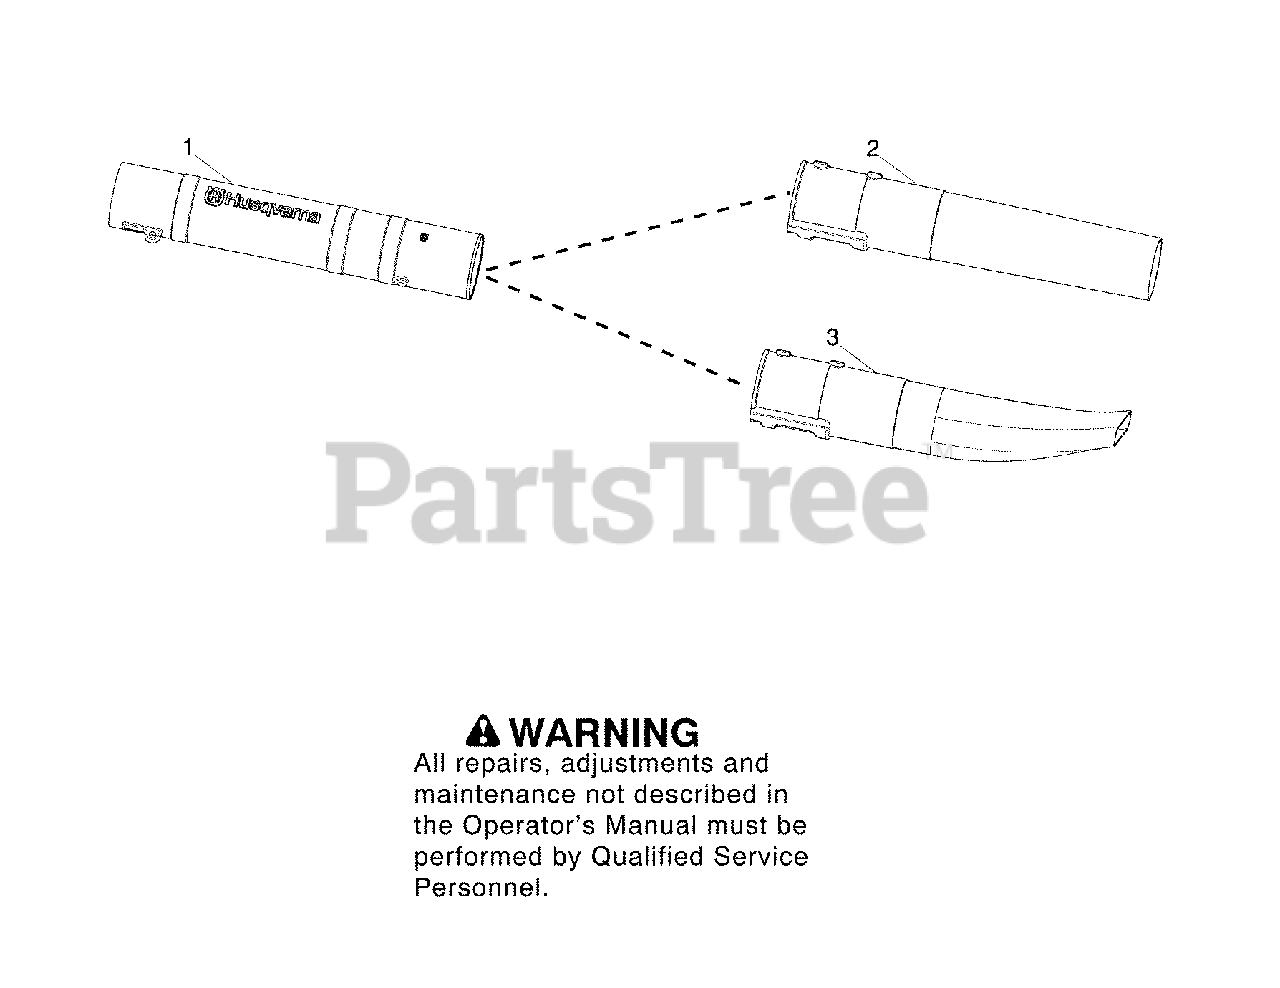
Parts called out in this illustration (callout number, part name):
1	Assy - Tube - Upper Blower w/barrier
2	Tube - Lower blower
3	Tube - Lower blower
